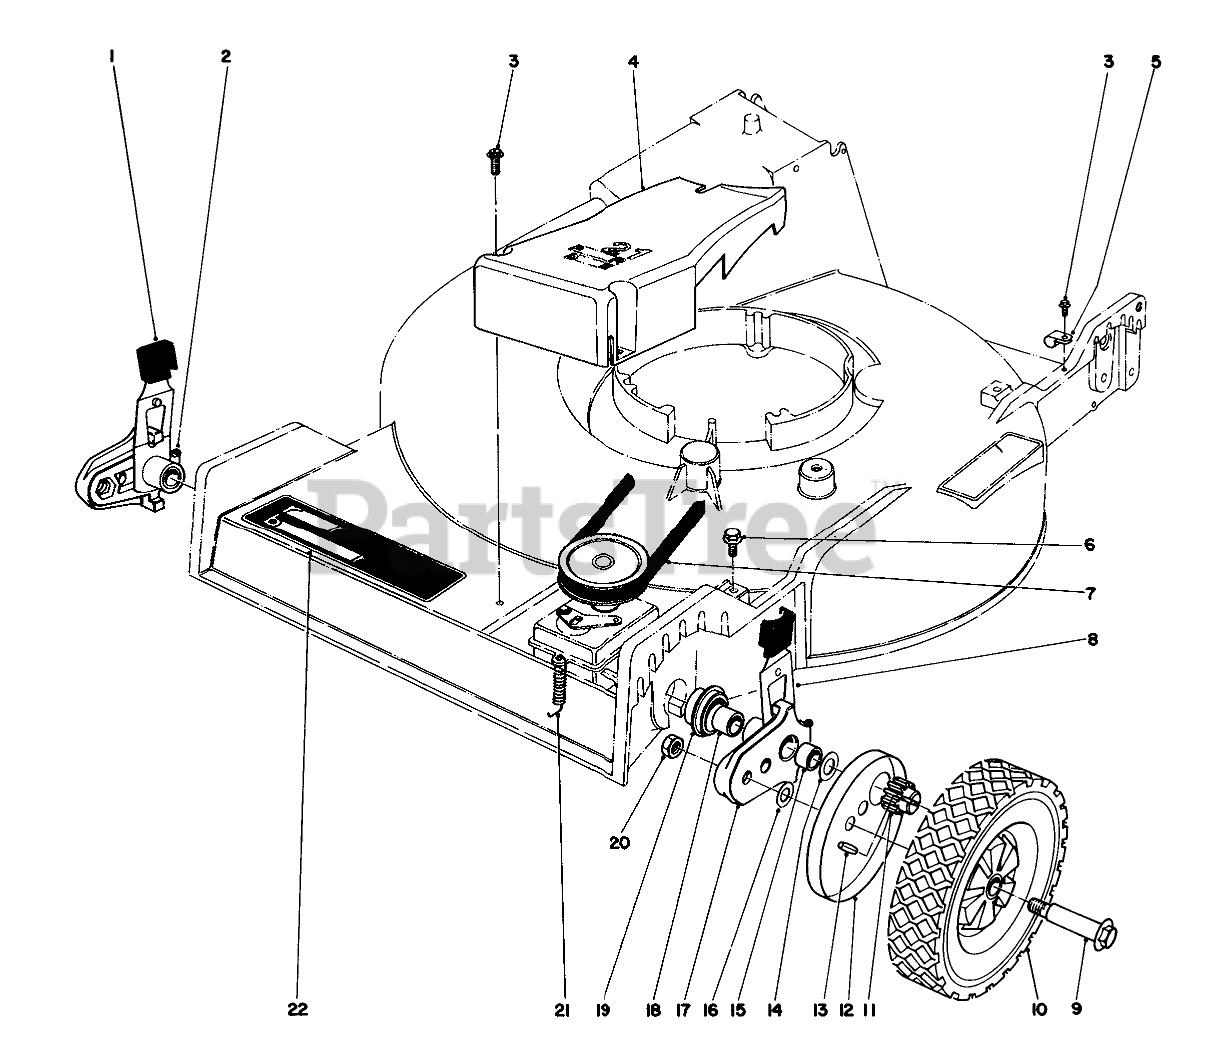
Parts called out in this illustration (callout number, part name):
1	KNOB-ARM
2	FITTING-GREASE
3	SCREW
4	Belt Cover
5	CLAMP-NYLON
6	SCREW-HWHTF
7	V BELT
8	SPRING ARM ASM SP
9	BOLT-WHEEL
10	Wheel & Tire Assembly
11	Pinion Gear
12	Cover-Wheel
13	Pin
14	WASHER-THRUST
15	Bushing
16	WASHER
17	Pivot Arm Assembly (Incl. Ref. #2, 15 & 18)
18	Bushing
19	END CAP
20	Nut
21	Spring-Tension
22	Decal-Deck
